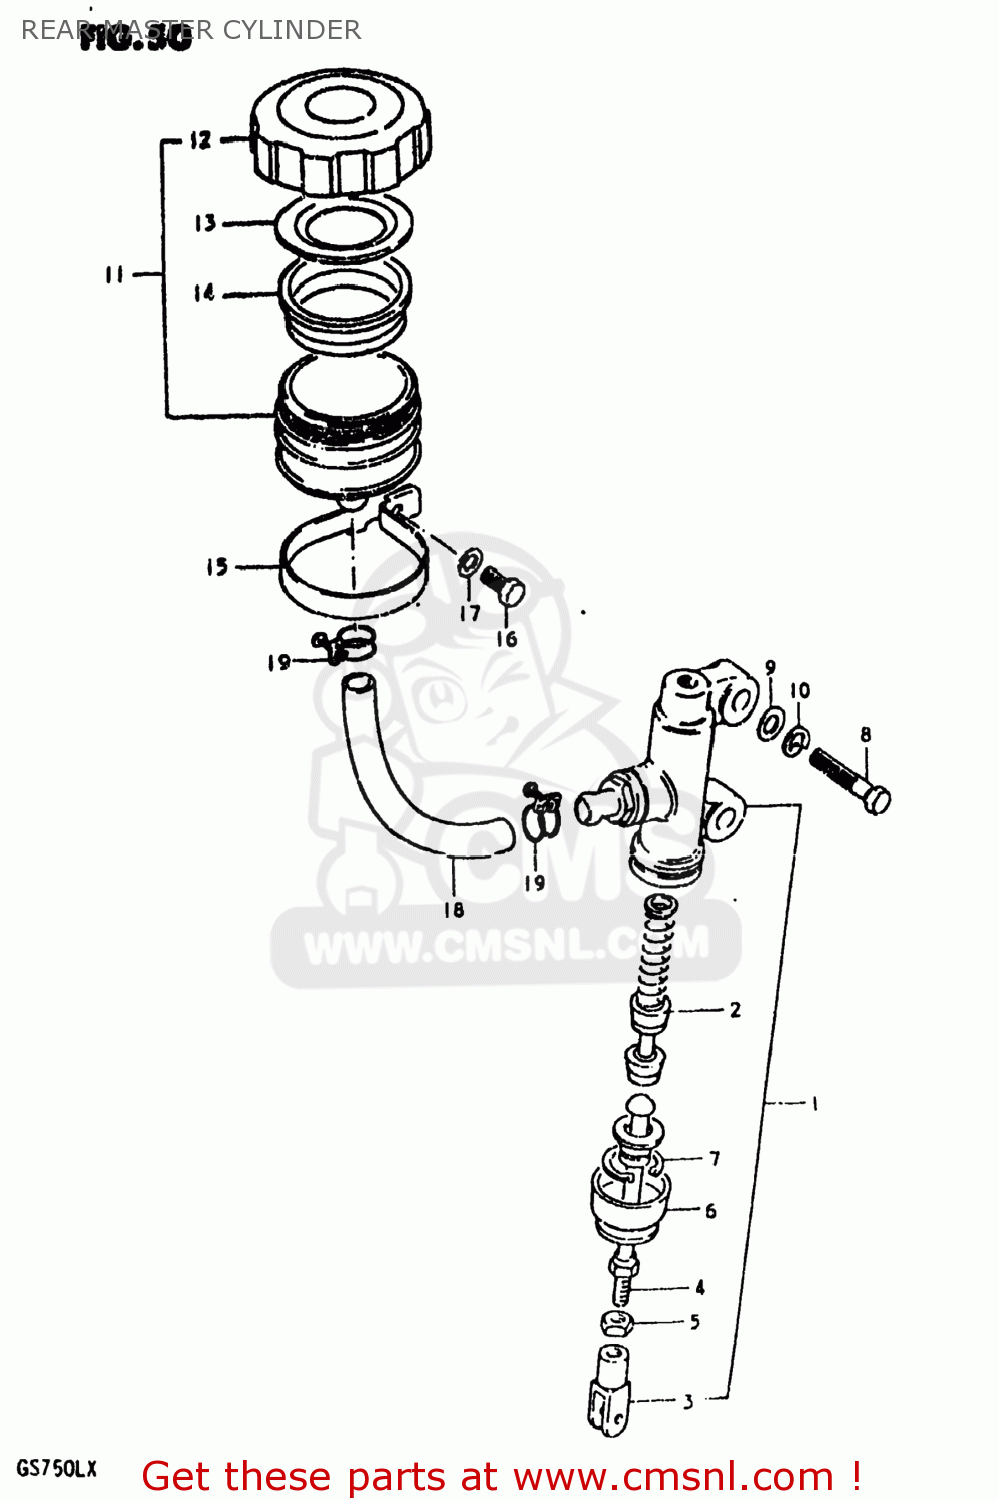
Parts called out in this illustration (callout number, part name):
1	CYLINDER ASSEMBLY,REAR MASTER
2	PISTON/CUP SET
3	YOKE
4	ROD,PUSH
5	NUT
6	BOOT
7	CIRCLIP
8	BOLT (8X30)
9	WASHER
10	LOCK WASHER
11	TANK ASSEMBLY,RESERVOIR
12	CAP
13	PLATE,DIAPHRAGM
14	DIAPHRAGM
15	CLAMP
16	BOLT, UPPER
17	LOCK WASHER
18	HOSE,RESERVOIR TANK
19	CLAMP
